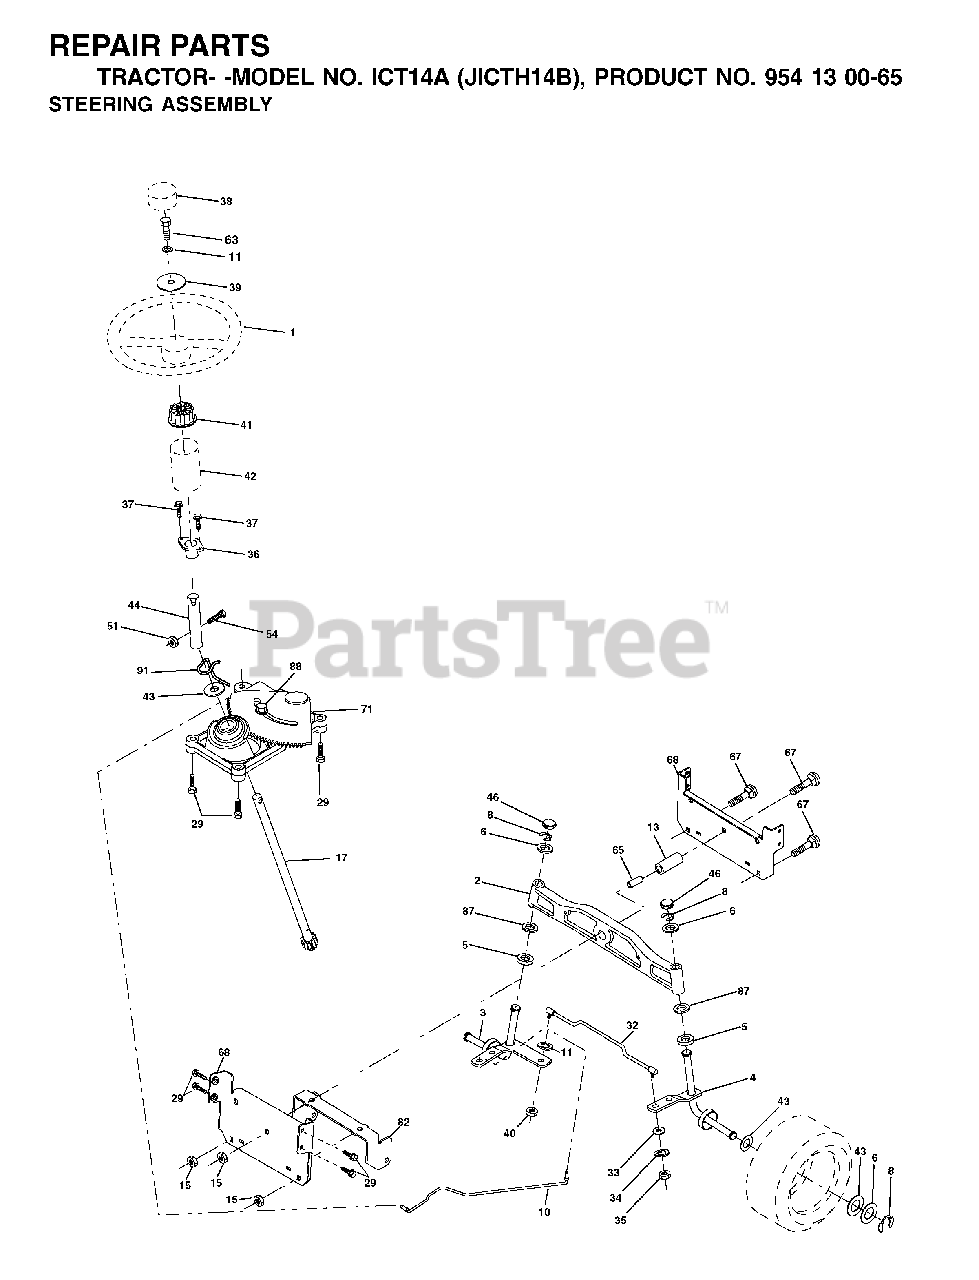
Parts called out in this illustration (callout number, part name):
2	AXLE ASM
3	SPINDLE.ASM.LH.15"TIRES
4	SPINDLE.ASM.RH.15"TIRES
8	RING CLIP
10	DRAGLINK.15".TIRES.2001
11	WASHER, LOCK 3/8
13	TUBE, PIVOT AXLE
15	NUT
17	SHAFT ASM
29	SCREW 3/8-16X3/4
32	ROD.ASM.TIE.BALL.JOINT.NOVAN
33	WASHER M
34	LOCKWASHER
35	NUT, CROWNLOCK
36	BUSHING, STEERING
39	WASHER 13/32 X 2-3/8 X 12 GA
40	GRIPCO NUT
41	STEERING WHEEL ADAPTOR
42	BOOT.STEERING.SHAFT.BLACK
44	EXT SHAFT STEERING
46	CAP.SPINDLE
51	NUT.71038.31-18.HEX.NYLOCK
54	BOLT.5/16-18X1-1/4 FULL.THREAD
65	SPACER BRACE AXLE
67	BOLT
68	BRACE.AXLE.15"TIRES
71	STEERING ASM
82	BRACKET
87	WASHER, FLAT .781 X 1 1/2"
88	BOLT, SHOULDER 7/16-20
91	CLIP.STEERING
